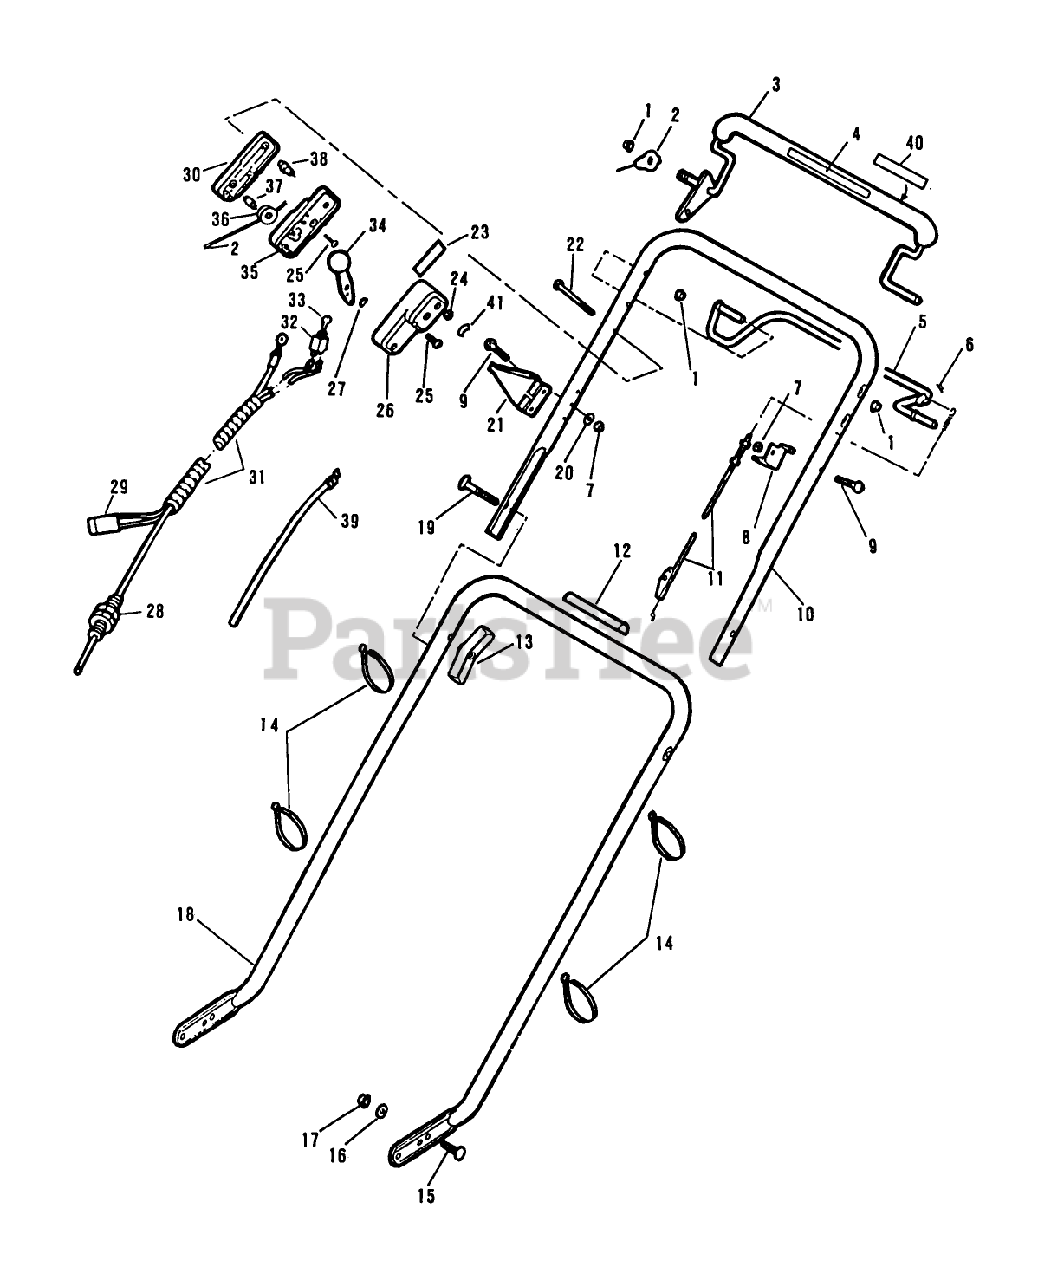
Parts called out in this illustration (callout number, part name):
2	CONTROL CABLE
3	CONTROL LEVER ARG
7	LOCKNUT E
8	ANCHOR C'DUIT TRO
11	CABLE - CONTROL
13	NUT-WING
17	NUT WING
20	WASHER
22	SCREW
24	NUT C/LOCK E
25	SCREW
26	CASE THROTTLE
27	WASHER-SPRING
28	CONTROL CABLE
30	OUTER CONTROL CASE
34	LEVER&KNOB AY WES
36	PULLEY PL
37	PIN SKF
38	COLUMN
39	CABLE TH'TTLE WES
